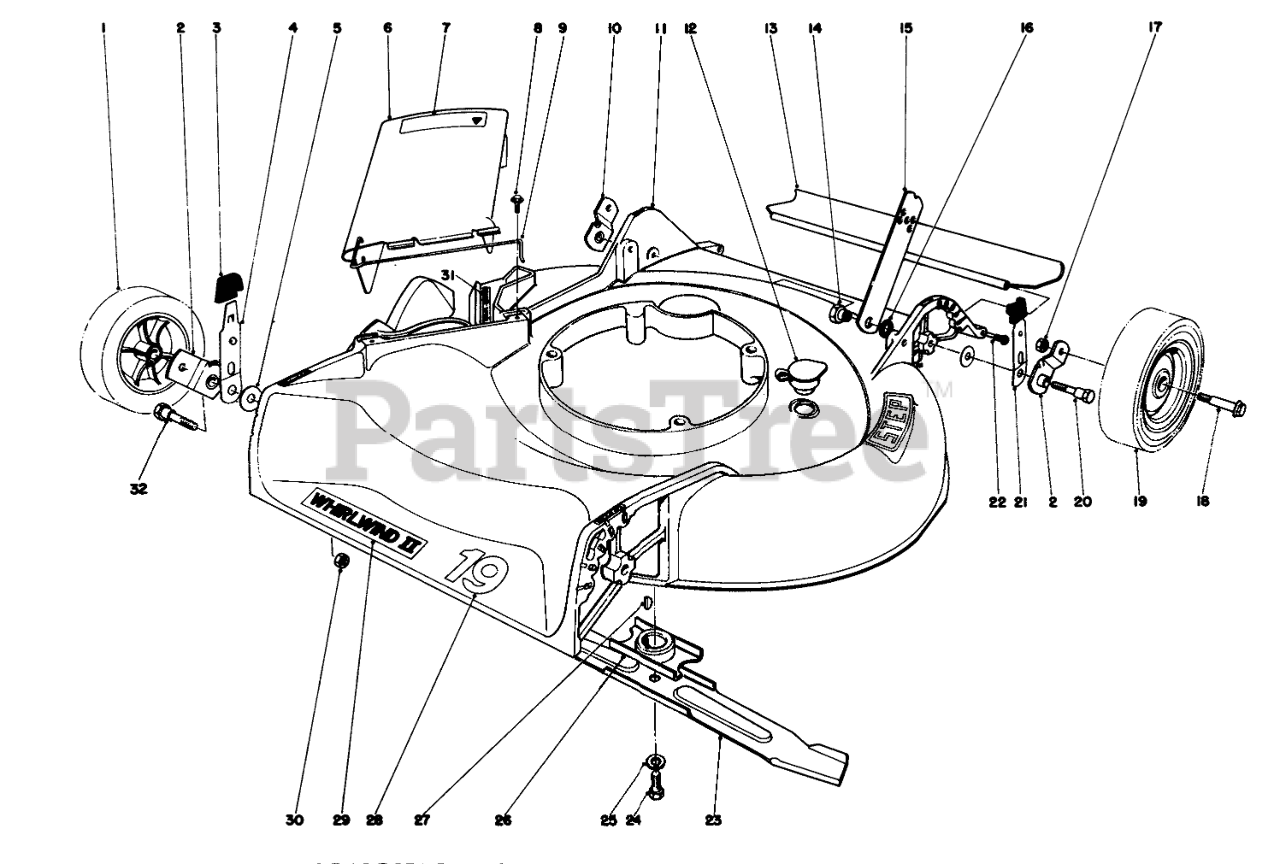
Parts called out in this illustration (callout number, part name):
1	Wheel & Tire Assembly
2	Pivot Arm
3	KNOB-ARM
4	SPRING ARM ASM
5	Washer
6	Deflector Assembly (Incl. Ref. # 7 & 9)
7	Decal Caution
8	SCREW
9	SPRING HINGE
10	Pivot Arm
11	Housing
12	Plug Washout
13	Rear Shield
14	HANDLE PIVOT NUT
15	Handle Latch
16	Spacer Handle Latch
17	Nut
19	Wheel & Tire Assembly
20	PIVOT SCREW
21	SPRING ARM ASM
22	SAFTEY SHIELD SCREW
23	Blade
24	SPECIAL SCREW
25	WASHER-LOCK
26	Blade Retailer
27	KEY-WOODRUFF
28	Decal-19"
29	Decal Whirlwind
30	Nut
31	Decal
32	PIVOT SCREW
